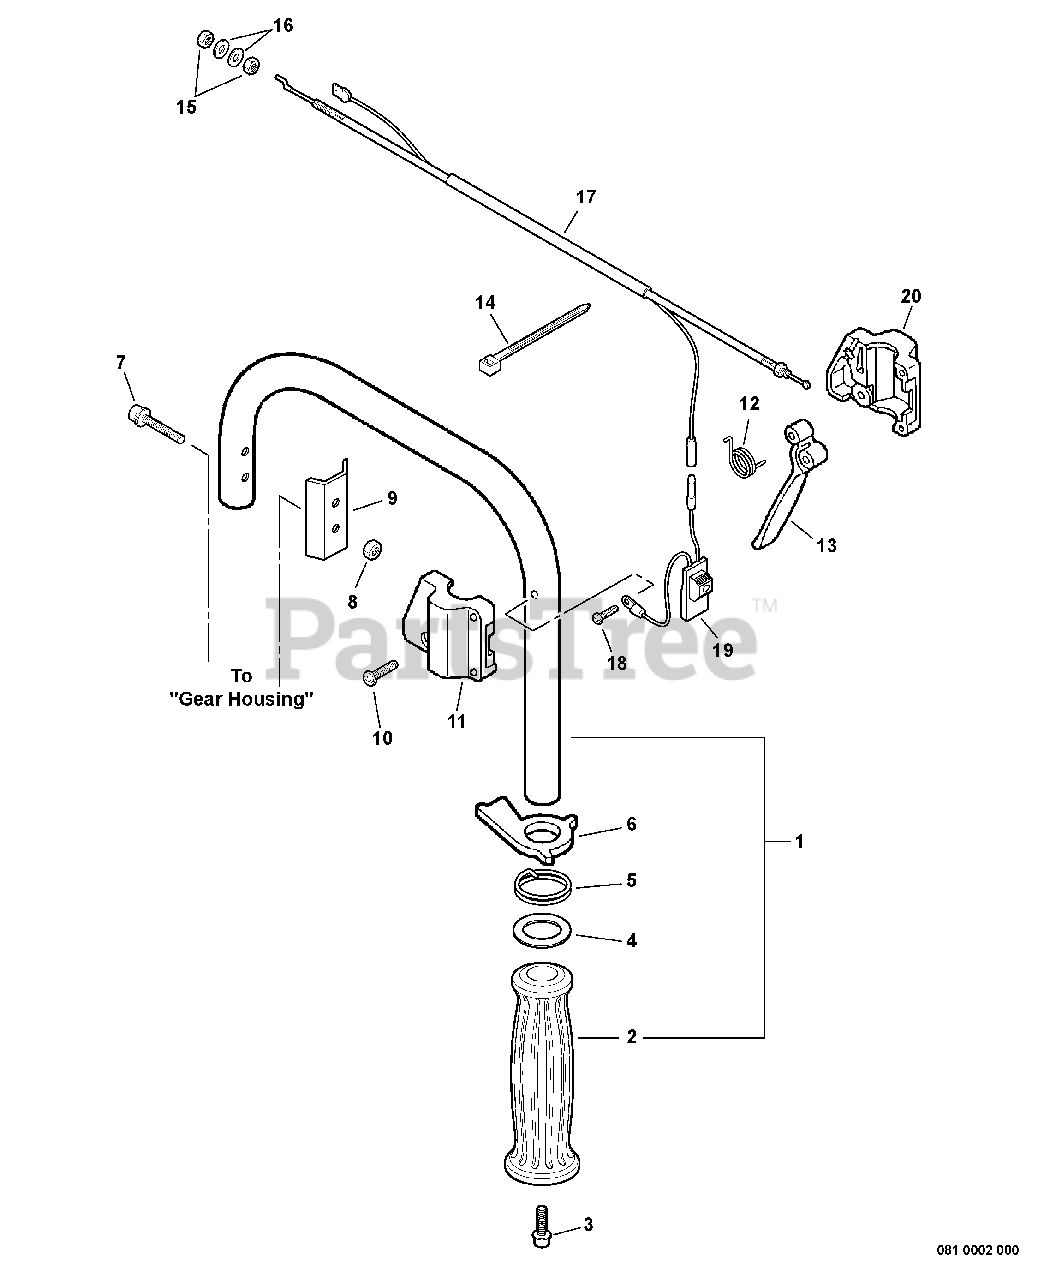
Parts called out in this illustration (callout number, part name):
1	HANDLE ASSY - REAR
2	GRIP, HANDLE
3	SCREW 5×16
5	SPRING, THROTTLE LOCKOUT
6	LOCKOUT, THROTTLE
7	BOLT M5×35
8	NUT, LOCK M5
10	SCREW 4×25
11	BRACKET, THROTTLE CONTROL - LEFT
12	SPRING, THROTTLE RETURN
13	CONTROL, THROTTLE
14	TIE, CABLE
16	WASHER 6.5×11.5×0.8
17	CONTROL CABLE ASSY
18	SCREW 4×30
19	SWITCH, ON-OFF
20	BRACKET, THROTTLE CONTROL - RIGHT
